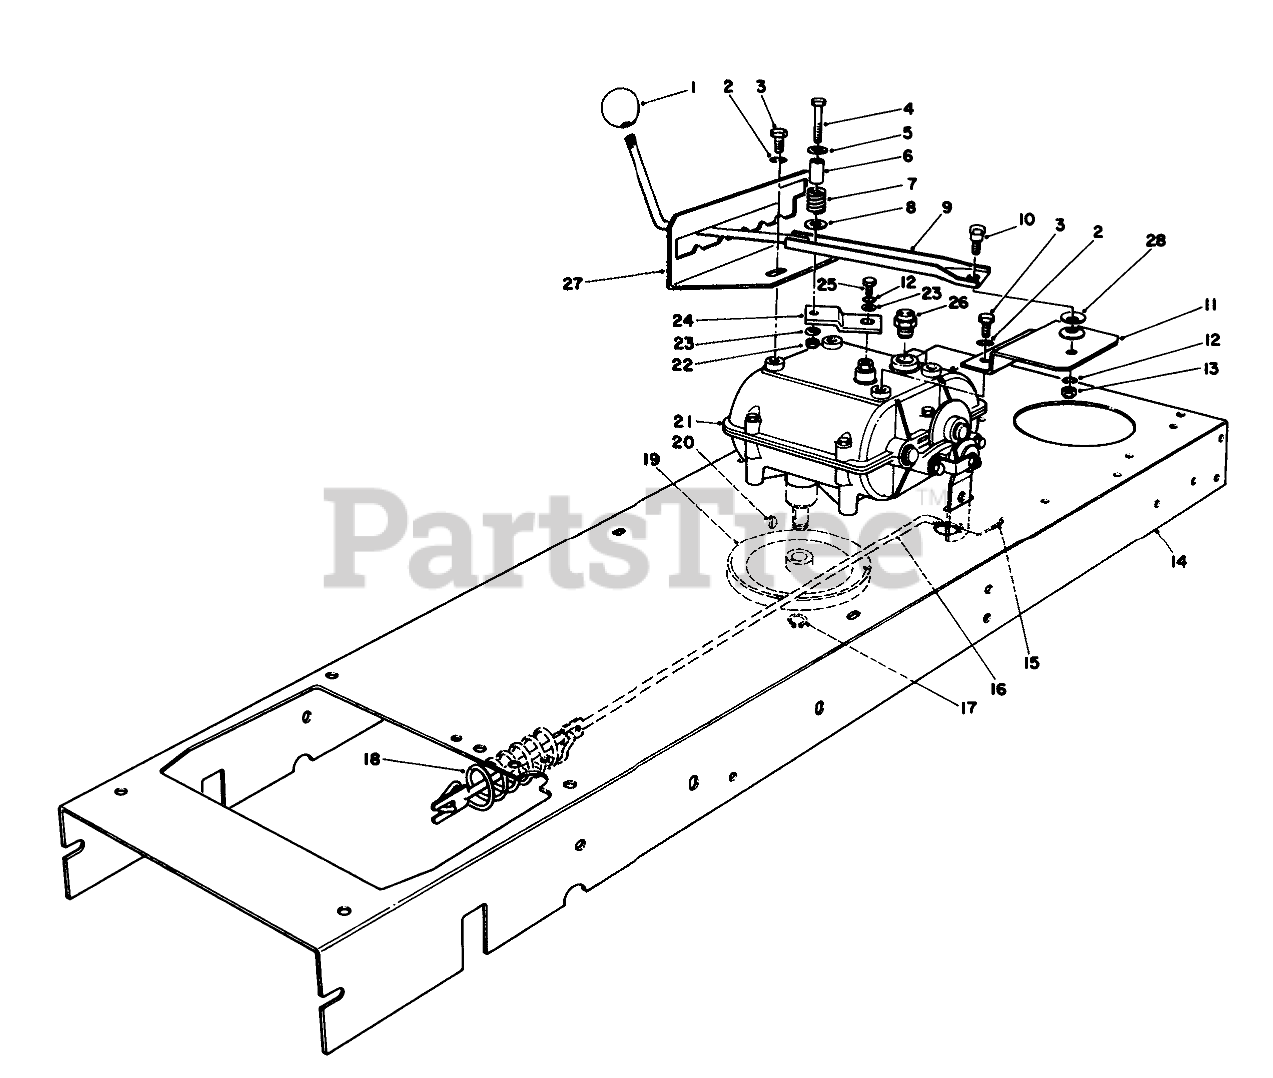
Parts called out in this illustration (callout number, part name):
2	WASHER-LOCK
3	SCREW-HWHTF
4	SCREW-HH
5	WASHER-FLAT
6	SPACER-SPLIT
7	SPRING-COMPRESSION
8	WASHER-FLAT
9	SHIFT LEVER WA B
10	SCREW-SHOULDER
11	SHIFT MTG BRKT
12	WASHER-LOCK
13	NUT-LOCK, NI
14	Frame-Main
15	PIN-COTTER
16	BRAKE ROD
17	RING-SNAP, EXTERNAL
18	EXT SPRING O
19	PULLEY
20	KEY-WOODRUFF
21	TRANSMISSION
22	NUT-LOCK, CONE
23	WASHER-FLAT
24	LEVER-SHIFT
25	SCREW-HH
26	NEUTRAL SWITCH
27	Gate-Shift
28	WASHER-BELLEVILLE
